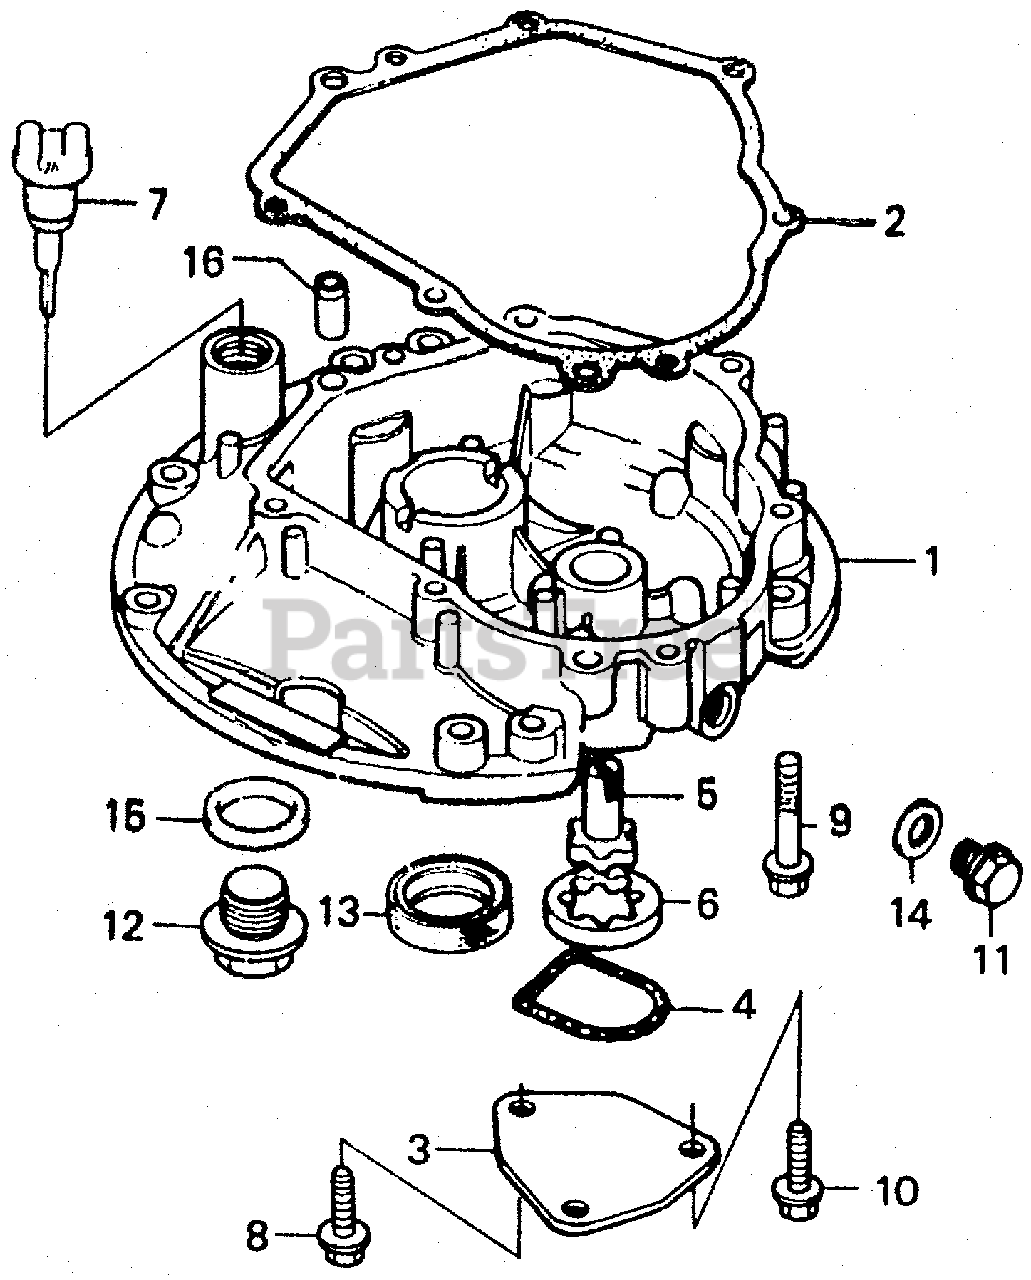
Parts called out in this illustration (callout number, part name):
2	GASKET, OIL PAN
3	COVER, OIL PUMP
4	O-RING, PUMP COVER (NOT AVAILABLE)
5	ROTOR (INNER) (NOT AVAILABLE)
6	ROTOR, OIL PUMP (OUTER)
7	CAP, OIL FILLER (NOT AVAILABLE)
8	BOLT, FLANGE (6X12) (CT200)
9	BOLT, FLANGE (6X32) (CT200)
10	BOLT, FLANGE (6X16) (CT200)
11	BOLT, DRAIN PLUG (12X15)
12	BOLT, OIL DRAIN (NOT AVAILABLE)
13	OIL SEAL (25X41X6)
14	WASHER, DRAIN PLUG (12MM)
15	WASHER, DRAIN PLUG (20MM)
16	PIN, DOWEL (8X14)
